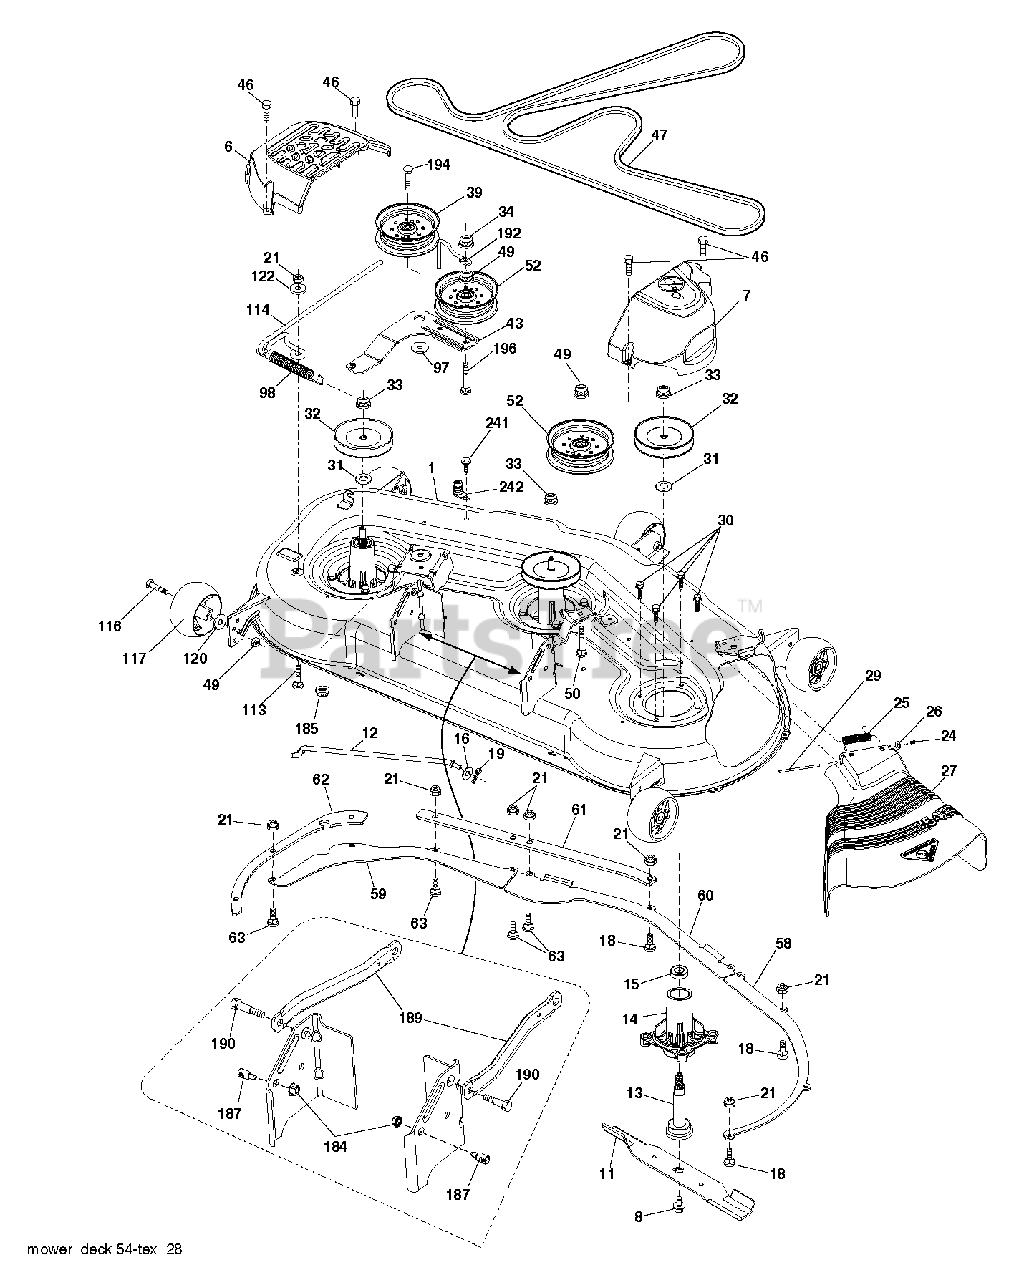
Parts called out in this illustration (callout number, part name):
1	DECK SVC 54"
6	COVER.MANDREL.LH.54"20
7	COVER.MANDREL.RH.54.20
8	BOLT.WASHER.ASM.7/16-2
11	BLADE.BAGGING.54"
11	54" MULCH BLADE
12	ROD.ANTI.SWAY.48/54"TE
13	SHAFT ASM MANDREL
14	HOUSING.MANDREL.4PT.
16	WASHER
18	BOLT
19	PIN.COTTER.5/16.BOW TI
21	LOCKNUT
24	CAP-SLEEVE LT
25	SPRING, TORSION
26	NUT PUSH M
27	DEFLECTOR
29	ROD.HINGE
30	SCREW, WASHER HEAD
31	WASHER.SPACER.MANDREL
32	PULLEY/MANDREL
33	NUT.FLANGE.LOCK.TOP
39	RB PULLEY.IDLER.4.50/HUB SPEC
46	SCREW.1/4-20X5/8
47	BELT.DRIVE.54."2006
49	NUT LOCK FLG 3/8-16 UNC
52	PULLEY.IDLER.2006
58	BAFFLE.RIGHT.54"
59	BAFFLE.LEFT.54"
60	BAFFLE CENTER 54" MOWER
61	PLATE.REIN.FRONT.BOLT54"X431
62	PLATE.REIN.SIDE.BOLT.54"X431
63	BOLT.CARRIAGE.5/16-18
98	SPRING, DECK DRIVE
114	ROD TENSION RELIEF
116	BOLT.SHOULDER.3/8-16X3-5/8.
117	WHEEL. GUAGE RALLY
120	WASHER
122	BUSHING.RELIEF.TENSION
184	NUT LOCK HEX FLANGE 5/16-18
185	NUT.LOCK.FLANGE.7/16
187	STUD.FASTNER.W/ANTI-ROTATE
189	ARM.SUSPENSION.MOWER
190	BOLT.SHOULDER
192	KEEPER.BELT.IDLER.54"T
194	BOLT.HEX.WASHER.HEAD.7/16-24X
241	SCREW.TT.#10-32X.5.3/8.FLANGE
242	PORT.WASHOUT
